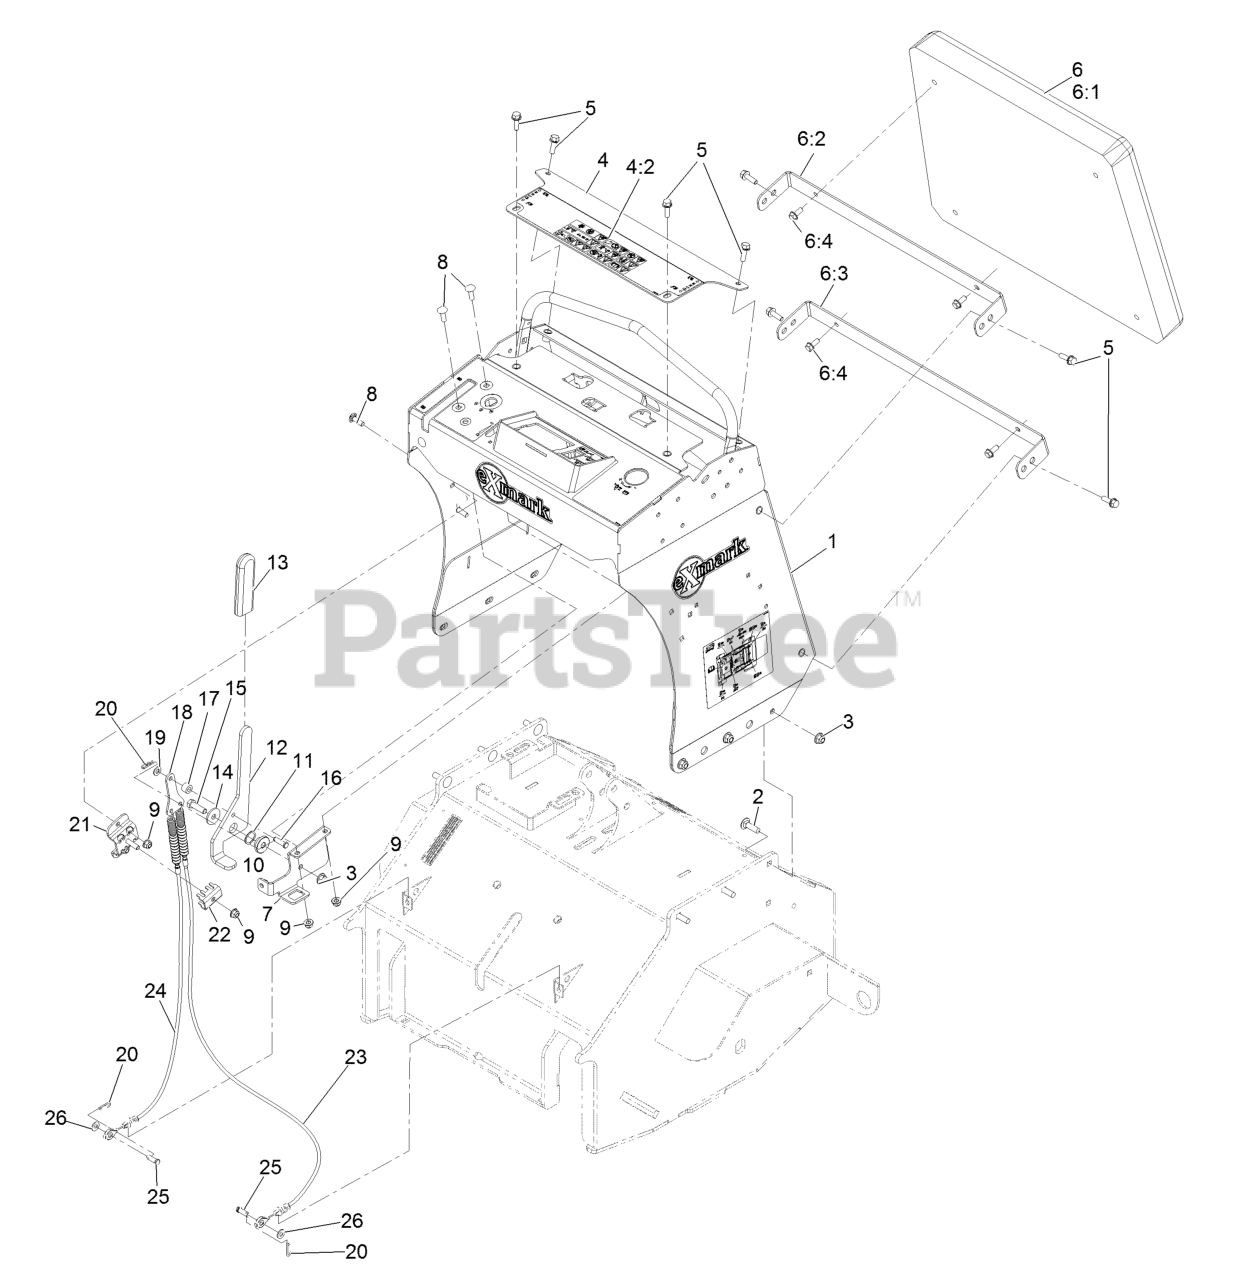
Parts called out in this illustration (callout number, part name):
1	Control Tower ASM
2	Bolt-Carriage 3/8-16 X 1 1/4
3	Nut-Nyloc 3/8-16 Flg
4	Control Panel ASM
4:2	Decal-Warning
5	Screw-HH Flg 5/16-18 X 1
6	Cushion ASM
6:1	Cushion-Grey
6:2	Bracket-Pad, Upper
6:3	Bracket-Pad, Lower
7	Bracket-Pivot, Brake
8	Bolt-Carriage 5/16-18 X 1 Sp
9	Nut-Nyloc 5/16-18 Flg
10	Pivot-Flange
11	Washer-Wave
12	Handle-Brake
13	Grip-Lever
14	Washer
15	Screw-HH 3/8-16 X 1 1/4
16	Pin-Yoke
17	Bushing
18	Yoke-Cable
19	Spacer-Nylon
20	Pin-Cotter
21	Mount-Cable, Brake
22	Clamp-Cable
23	Cable-Brake, LH
24	Cable-Brake, RH
25	Pin-Clevis 5/16 X 3/4
26	Washer-5/16 SAE
